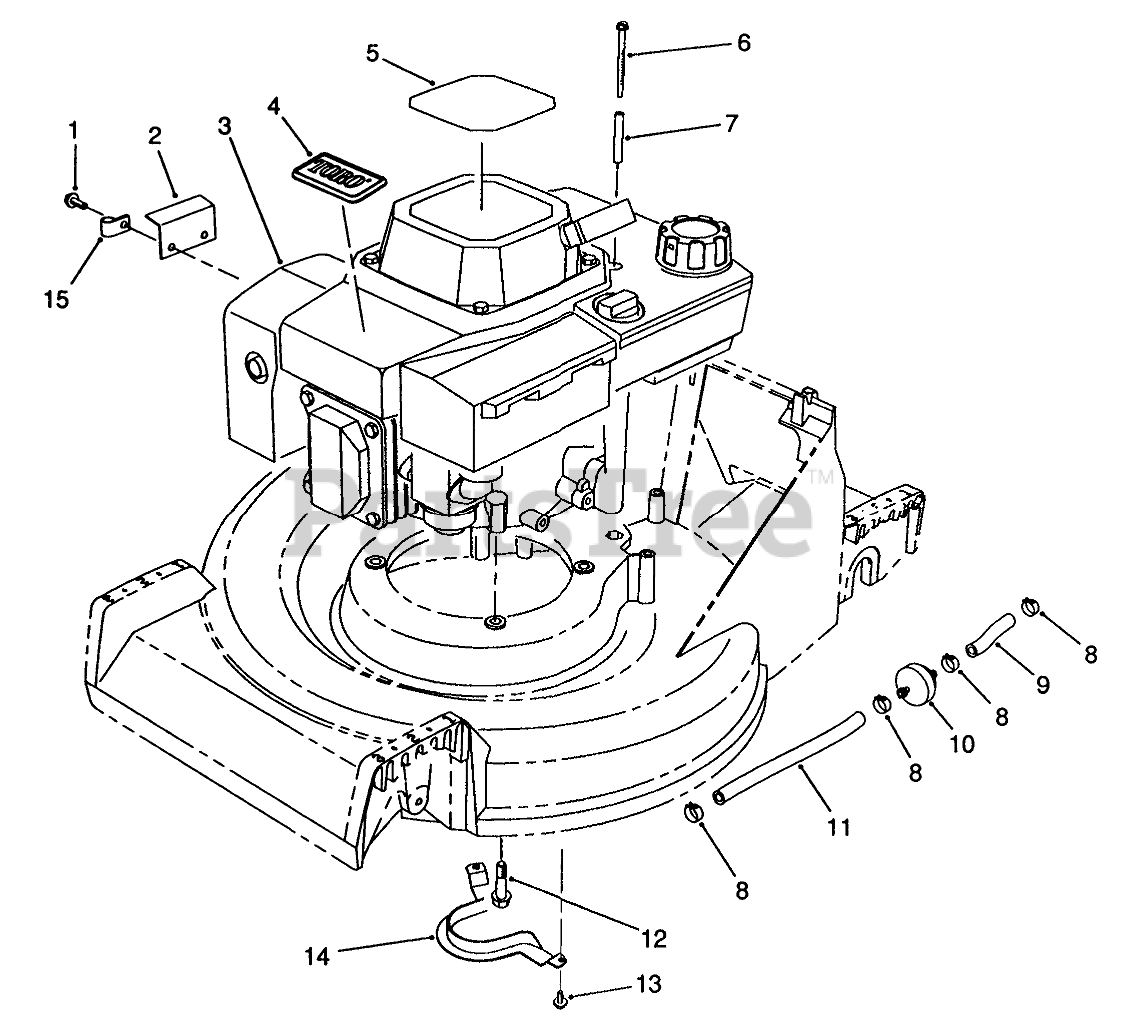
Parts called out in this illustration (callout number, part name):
1	THO FORM SCREW M6 X 1
2	FLYWHEEL SHIELD
3	Engine-OHV
4	TORO LOGO PLT
5	DECAL-HV INT'L
6	THRD FORMING SCREW
7	TUBULAR SPACER
8	CLAMP-FUEL LINE
9	LINE-GAS
10	FILTER-FUEL
11	HOSE-FUEL
12	SCREW-HWHTF
13	SCREW-HWHTF
14	Guide-Belt
15	CLAMP-R
